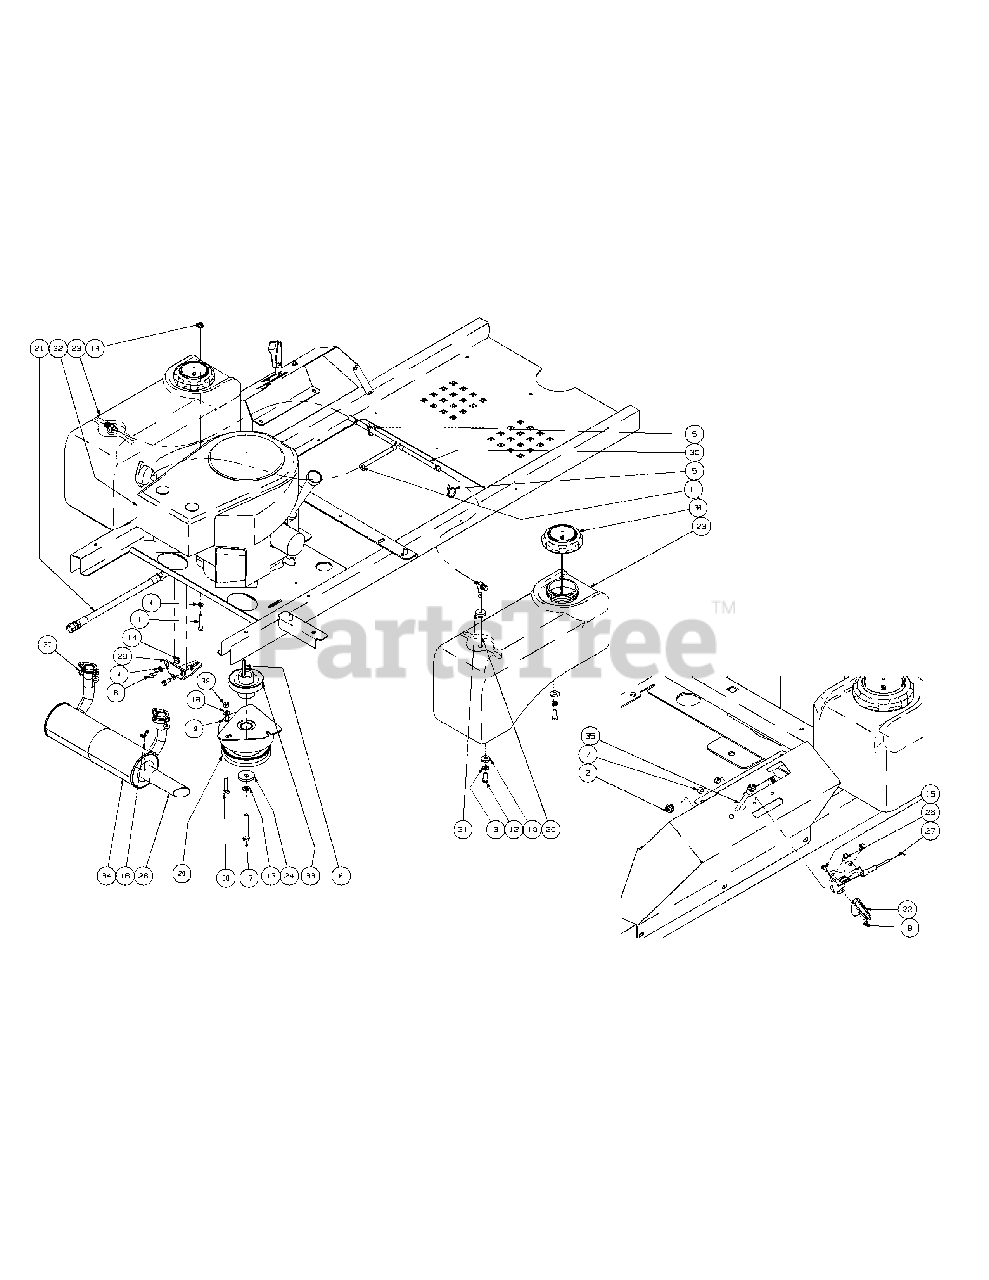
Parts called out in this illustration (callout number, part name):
1	HHCS, 5/16-18, 1-3/4
2	Jam Nut, 3/8-24
3	Lock Washer, 3/8 Zinc
4	Flat Washer, 5/16
5	Cable Tie, 3/16 x .05 x 7.4
6	Hex Cap Screw, 5/16-18 x .75
7	Lock Nut, Nylon Insert, 10-32
8	Key, .25 x .25 x 2.00
9	Nut, w/ Star Washer
10	Flat Washer, .390 x 1.00 x .180
11	Hose Clamp, SAE #4: 1/4-5/8, SS
12	Hex Cap Screw, 3/8-16 x .88
13	Lock Washer, 7/16
14	Lock Nut, Hex Flange, 5/16-18
15	Machine Screw, 8-32 x .375
16	Screw, 8-32 x .375, Hex Washer
17	Hex Cap Screw, 7/16-20 x 3.00
18	Lock Washer, 5/16
19	Washer, 3/8 x .738 x .063
20	Fuel Pickup Fitting
21	Oil Drain Extension Hose
22	Throttle Control Knob
23	Fuel Tank
24	Flat Washer, 7/16 ID x 1.75 OD x .250
25	Screw, #10-32 x 0.500
26	Exhaust Pipe
27	Throttle Control Cable
28	Clutch Retainer Assembly
29	Electric Clutch
30	Fuel Hose Assembly includes:
30	Hose, 1/4" Fuel Line (70 inches)
31	Fuel Tank Groment
32	21HP Kawasaki Engine
33	Transmission Drive Pulley
34	Kawasaki Muffler
35	Choke Cable
37	Nut, M8-1.25, Hex Flange
38	Carriage Bolt, 5/16-18 x 1.75
39	Hex Nut, 5/16-18
